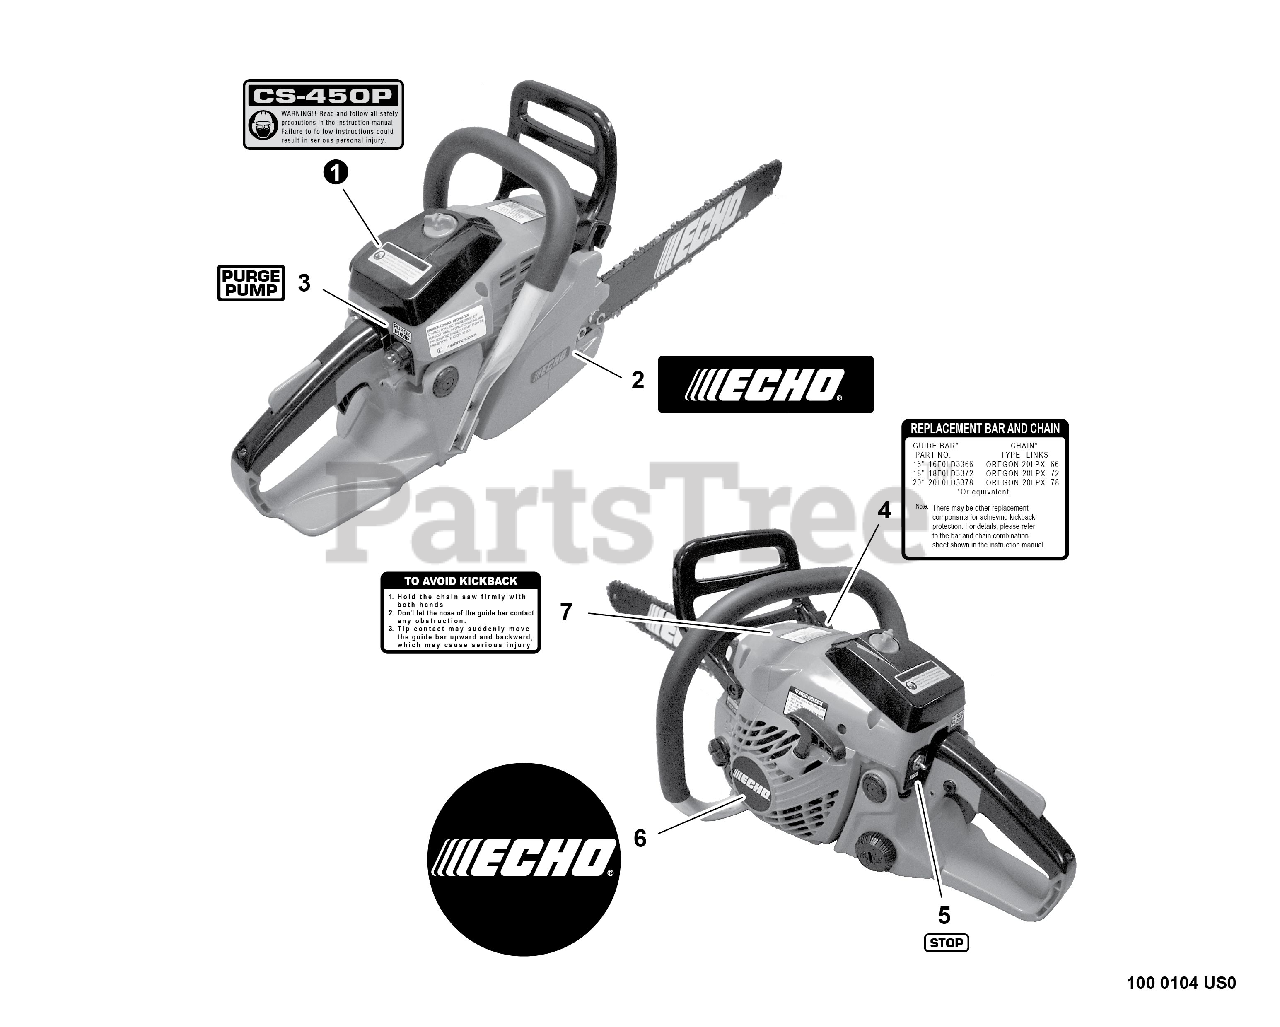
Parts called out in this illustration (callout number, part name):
1	LABEL - MODEL CS-450P
2	LABEL - ECHO
3	LABEL - PURGE PUMP
4	LABEL - BAR & CHAIN
5	LABEL - STOP
6	LABEL - ECHO
7	LABEL - KICK BACK
